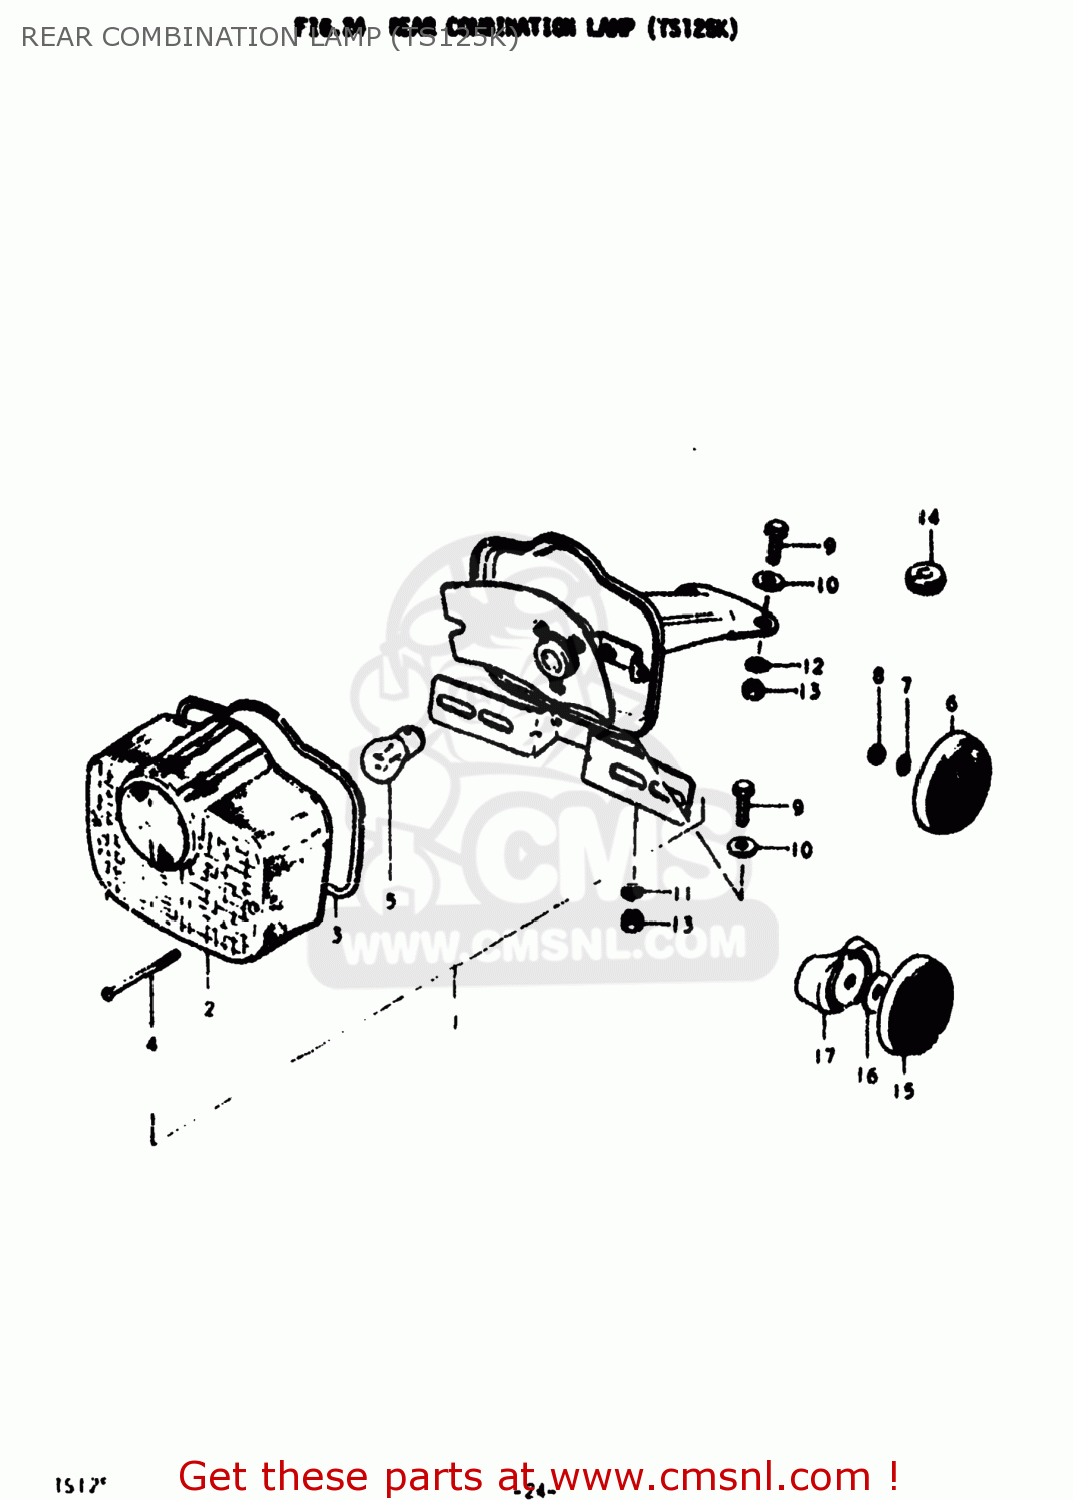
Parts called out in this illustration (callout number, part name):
1	LAMP ASSEMBLY,REAR COMBINATION
2	GASKET (NAS)
3	GASKET (NAS)
4	SCREW
5	BULB(6V32/3CP,STANLEY)
6	REFLECTOR,REFLEX
7	LOCK WASHER
8	NUT
9	BOLT 6X22
10	WASHER
11	LOCK WASHER
12	LOCK WASHER
13	NUT
14	GROMMET
15	REFLEX REFLECTOR ASSEMBLY
16	WASHER
17	SPACER
